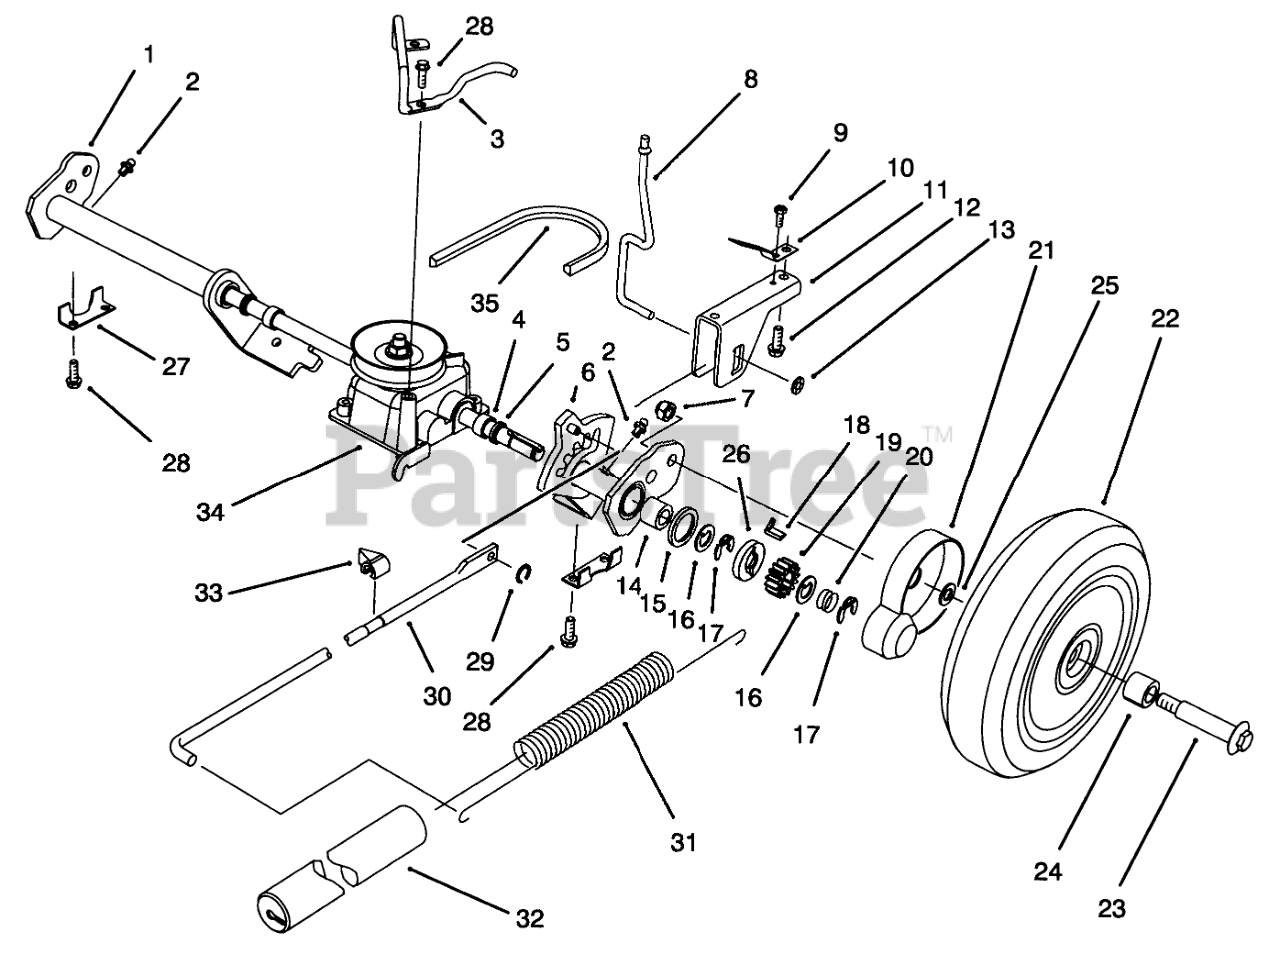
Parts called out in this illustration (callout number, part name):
1	Rear Pivot Assembly R.H. (Incl. Ref. #2, 4, 5 & 14)
2	FITTING-GREASE
3	Retainer Belt
4	BUSHING
5	SEAL-OIL
6	Rear Pivot Assembly L.H. (Incl. Ref. #2, 4, 5 & 14)
7	NUT-HEX
8	TRIGGER ROD
9	SCREW 8 - 32 X 250
10	SPRING - TRIGGER RET
11	SADDLE - HOC
12	SCREW
13	PUSHNUT
14	BEARING-ROLLER
15	RING-FRICTION
16	WASHER-THRUST, KEYED
17	RING-CLIP, LOCKING
18	KEY-ROCKING, LH
19	GEAR-PINION
20	SPRING-COMPRESSION
21	COVER-WHEEL
22	Wheel, Tire & Gear Assy. (Incl. Ref. #24)
23	BOLT-WHEEL
24	BUSHING
25	SPACER-COVER, WHEEL
26	WASHER-CLUTCH
27	REAR SECURING PLATE
28	SCREW-HWH
29	GRIP RING
30	LINK ROD
31	SPRING-COUNTERBALANCE
32	COVER-SPRING
33	INDICATOR-HEIGHT OF CUT
34	V-BELT
35	Gearcase Assembly (Incl. Ref. #36)
36	Bracket-Traction
